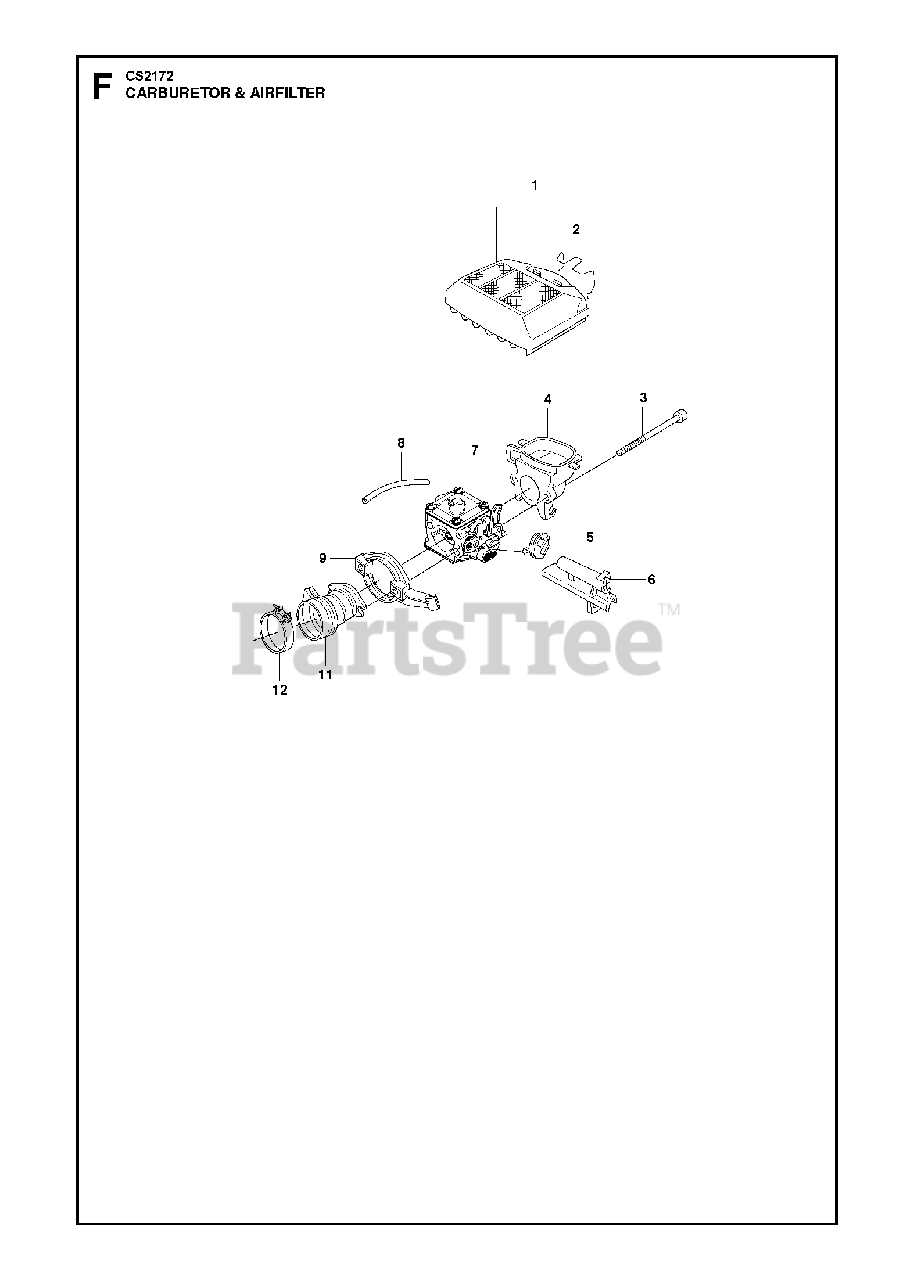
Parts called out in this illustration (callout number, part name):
1	AIR FILTER ASSY
2	AIR FILTER CLIP
4	FILTER HOLDER
6	GUIDE SLEEVE CARB
7	CARBURETOR
11	INLET PIPE
12	HOSE CLAMP
